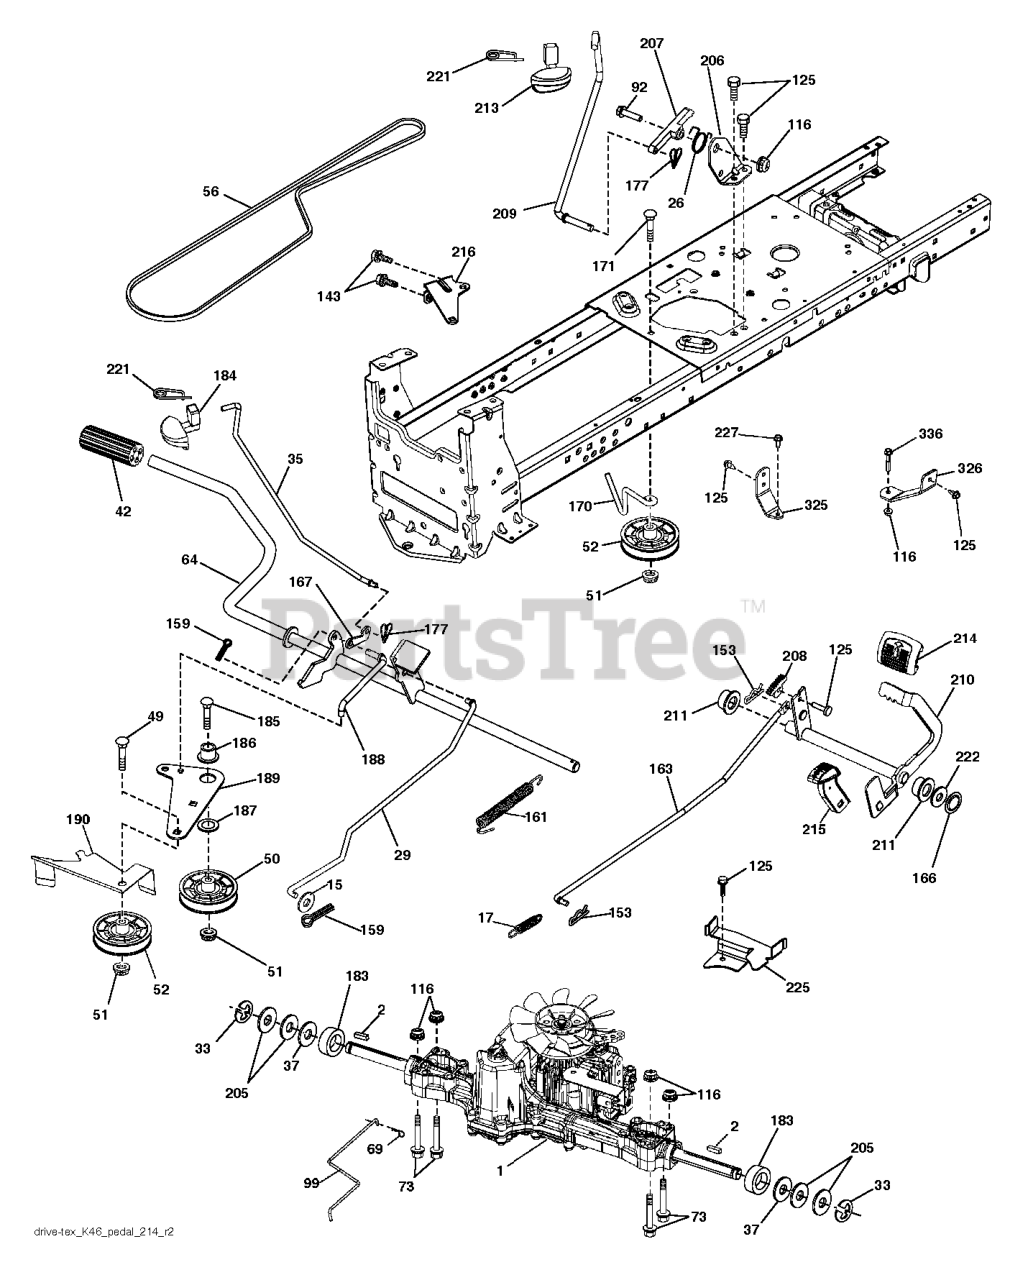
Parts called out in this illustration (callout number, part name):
1	PLUNGER.ASM.LIFT.LVR.BLK.17.32
2	SHAFT ASM R HANDLE
3	PIN GROOVE.
4	RETAINING RING LT
6	BEARING.NYLON
8	PLUNGER BUT KIT
11	LINK LIFT LH
12	LINK LIFT RH
13	RETAINER-SPRNG RB
15	LINK.SUSPENSION.FRONT
16	NUT.HEX.JAM.1/2-13
18	NUT.LK.W/WSH.1/2.
19	ARM.REAR.SUSPENSION
20	PIN.COTTER.7/16.BOW TI.
25	SPRING**
26	RETAINER CLIP
27	ROD ADJ LIFT
28	NUT
29	KNOB INF 3/8-16
31	BEARING.PIVOT.LIFT
32	NUT CROWNLOCK 3/8-24
36	POINTER, HEIGHT INDICATOR(2 2)
38	SCREW 5/16-18X1
41	HEIGHT INDICATOR
49	NUT.HEX.FLANGE.3/8-16.LOCKNUT
50	NUT PUSH M
